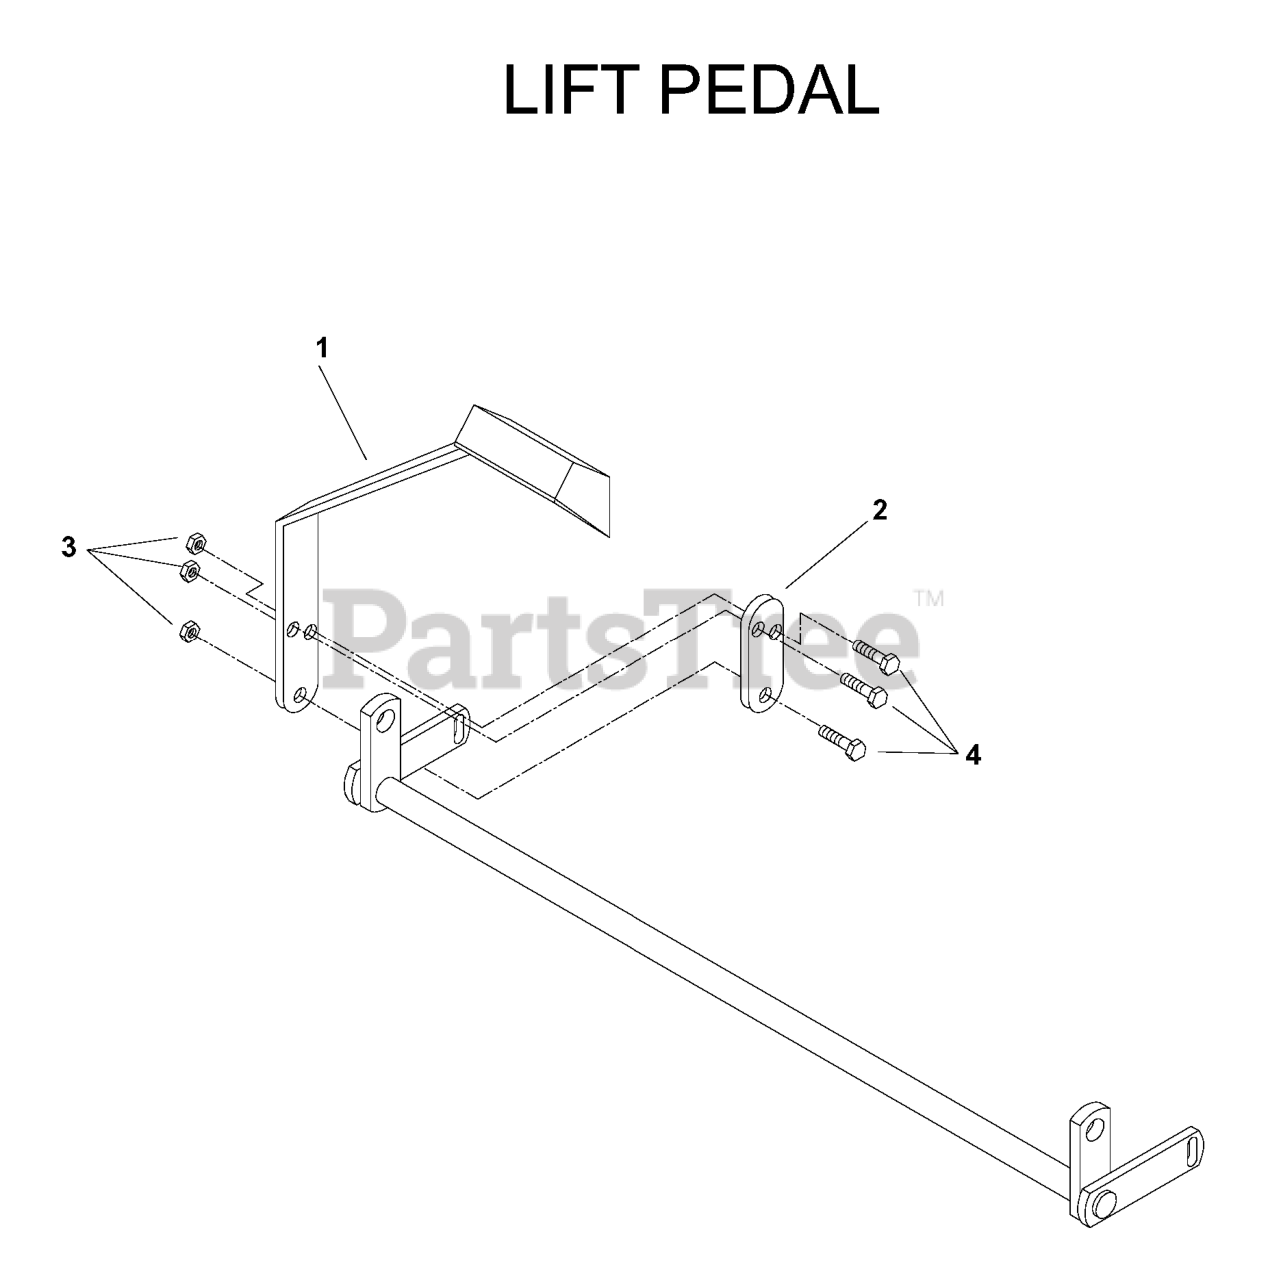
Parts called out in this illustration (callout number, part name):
1	LIFT PEDAL W/PAD
2	TIGHTENING PLATE
3	NUT 3/8-16 NYLOC
4	HCS 3/8C X 1 1/2
